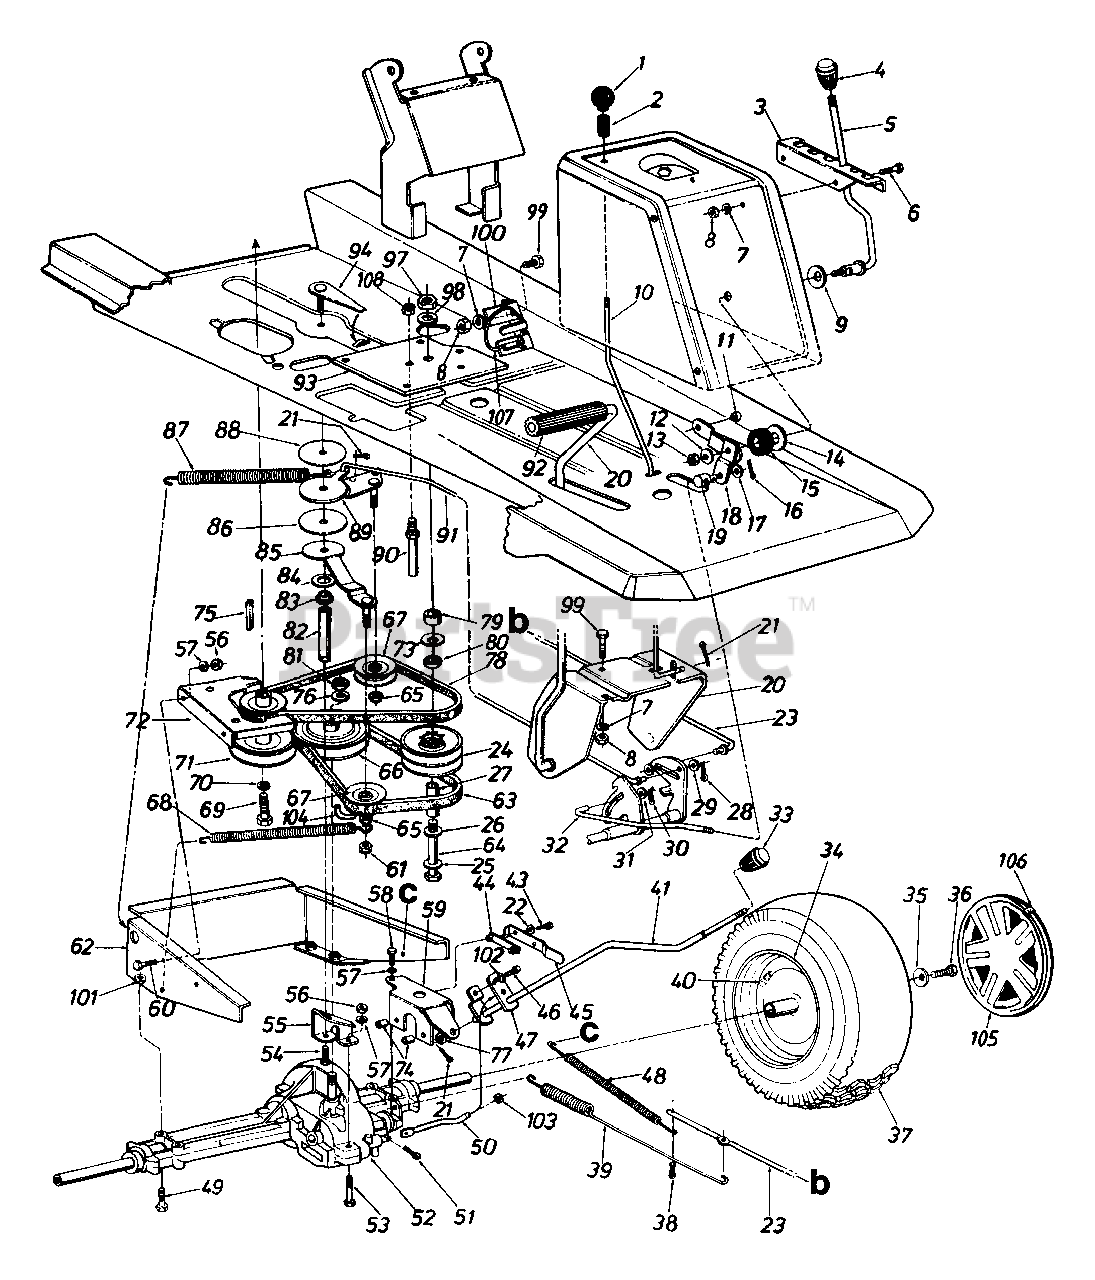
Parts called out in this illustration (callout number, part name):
1	Ball Knob 1/4 - 20 Thd. 1.25"
2	Compression Spring
5	Speed Control Lever
6	Truss Mach. Scr. 5/16 - 18 x .75" Lg.
7	L-Wash. 5/16" I.D.
8	Hex Nut 5/16 - 18 Thd.
9	Bell-Wash. .345" I.D. x .88"
10	Brake Locking Rod
12	Bell-Wash. .345" I.D. x .08"
13	Hex Cent. L-Nut 5/16 - 18 Thd.
14	FL-Wash. .531" I.D. x 1.25" O.D.
15	Rubber Washer
16	Intern. Cotter Pin 1/2" Dia.
17	FL-Wash. .34" I.D. x .68" O.D.
18	Speed Control Lever Brkt. Ass'y.
19	Ferrule - Engagement
20	Clutch/Brake Pedal Ass'y.
21	Cotter Pin 3/32" Dia. x .75"
22	Plastic Washer
23	Brake Rod
24	Variable Speed Pulley Ass'y.
25	FL-Wash. .4" I.D. x 1.25" O.D.
26	Thrust Brg. 1.25" O.D. x .56" I.D.
27	Spacer Sleeve 2.71"
28	Cotter Pin 1/8" Dia. x 1.25"
29	FL-Wash. .34" I.D. x .60" O.D.
30	Intern. Cot-Pin 5/16" Dia.
31	FL-Wash. .34" I.D. x .60" O.D.
32	Speed Control Link
33	Shift Knob
35	Bell-Wash. .345" I.D. x .88"
36	Hex L-Bolt 5/16 - 24 x .75" Lg.
38	Cotter Pin 1/8" Dia. x 1.25"
39	Extension Spring 17.0" Lg.
40	Air Valve
44	Insulator Nut
45	Spring Switch
46	Hex Bolt 1/4 - 20 x .50" Lg.
47	Shift Lever Adjusting Link
48	Ext. Spring 8 1/4" Lg.
49	Hex Bolt 5/16 - 18 x 2.5" Lg.
50	Shift Rod
51	Intern. Cotter Pin
52	Transaxle
53	Hex Bolt 1/4 - 20 x 1.75" Lg.
54	Hex Bolt 3/8 - 24 x .75" Lg.
57	L-Wash. 1/4" I.D.
58	TT-Tap Scr. 1/4 - 20 x 1.5" Lg.
59	Shift Lever Support Brkt.
60	Hex Bolt 1/4 - 20 x 1.00" Lg.
61	Hex L-Nut 3/8 - 24 Thd.
64	Hex Bolt 3/8-16 x 4.5" Lg.
65	Hex Ins. L-Nut 3/8 - 24 Thd.
66	V-Pulley
67	V-Belt Idler .38" I.D. x 3.06"
68	Ext. Spring .50" O.D. x 6.37"
69	Hex Bolt 7/16 - 20 x 1.00" Lg.
70	L-Wash. 7/16" I.D.
71	Engine Pulley
72	Upper Eng. Belt Guard
73	Bell-Wash. .4" I.D. x 1.12" O.D.
74	Spacer .256" I.D. x .50" O.D.
75	Sq. - Key 1/4" x 2.00" Lg.
76	Bell-Wash. .567" I.D. x 1.125"
77	FL-Wash. .469" I.D. x .88" O.D.
78	V-Belt
79	Spacer 1.00" x .380" O.D.
80	Thrust Wash. .56" I.D. x 1.25" O.D.
81	Hex Jam Nut 9/16 - 18 Thd.
82	Torque Rod
83	Flange Bearing .378
84	FL-Wash. .640" I.D. x 1.24"
85	Idler Bracket Ass'y.
86	Thrust Wash. .635" I.D.
87	Extension Spring 7.58" Lg.
88	Thrust Wash. .385" I.D.
89	Idler Bracket Ass'y. For Clutch
90	Belt Guard Pin 3/8 - 16 x 2.75" Lg.
91	Clutch Rod
92	Foot Pad
98	L-Wash. 3/8 Heavy Duty
99	Hex Bolt 5/16 - 18 x .75" Lg.
100	Speed Control Rod Brkt.
101	Hex Sems Nut 5/16 - 18 Thd.
102	Bell-Wash. .265" I.D. x .75" O.D.
103	Push on Retaining Ring
104	Belt Guard
105	Hub Cap - Beige
106	Spring Clip
107	Comp. Spring Clip
108	Hex Top L-Jam Nut 3/8 - 16 Thd.
